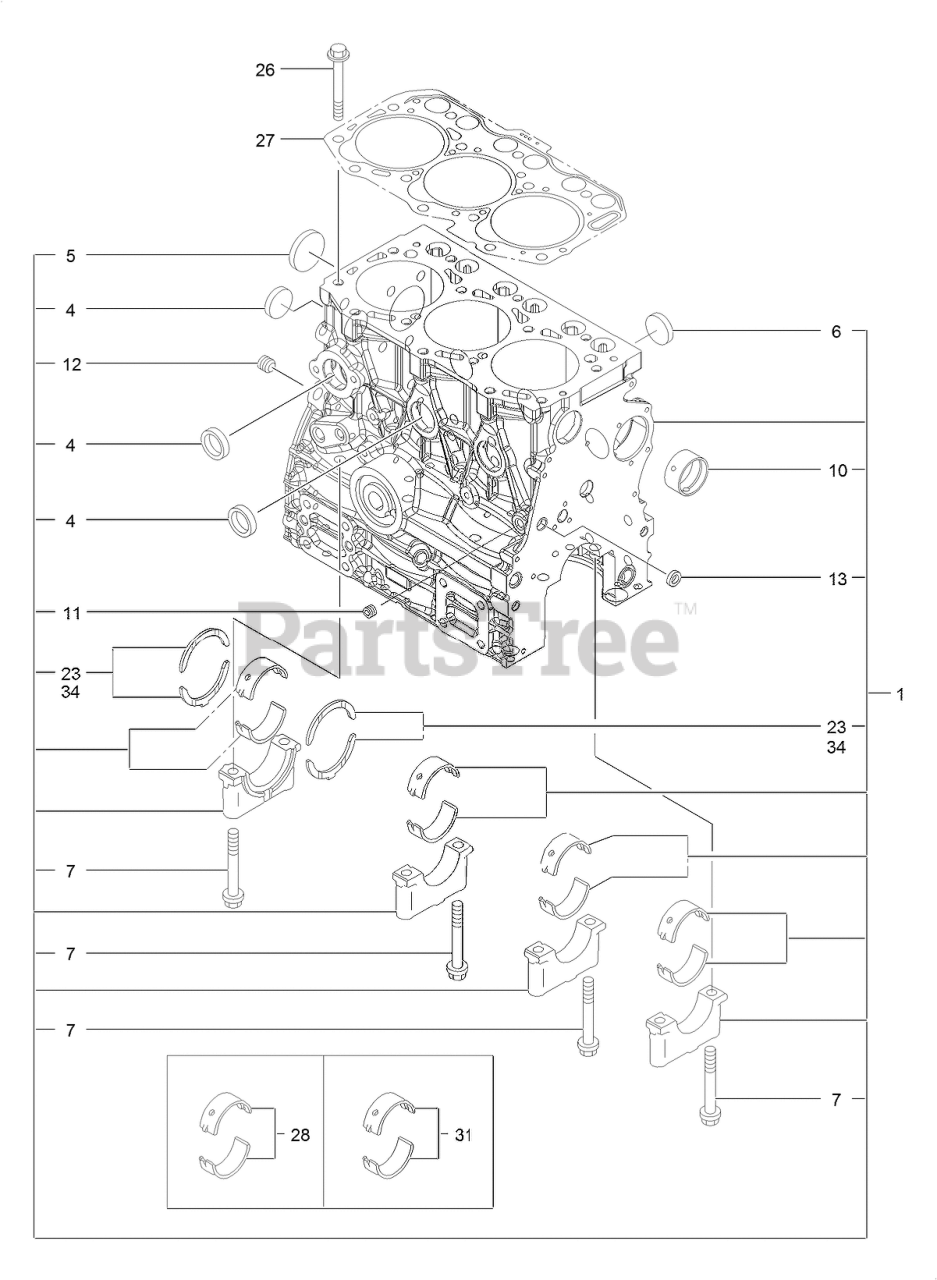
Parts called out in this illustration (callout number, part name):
1	BLOCK ASM-CYLINDER
4	PLUG, CUP TYPE 30
5	PLUG-DISH
6	PLUG-CUP TYPE 25
7	BOLT-METAL CAP
10	BUSH-CAMSHAFT
23	BEARING ASSY-THRUST
26	BOLT, CYLINDER HEAD
27	GASKET SET-HEAD
28	BEARING ASSY-MAIN
31	BEARING ASSY-MAIN
34	BEARING-THRUST
